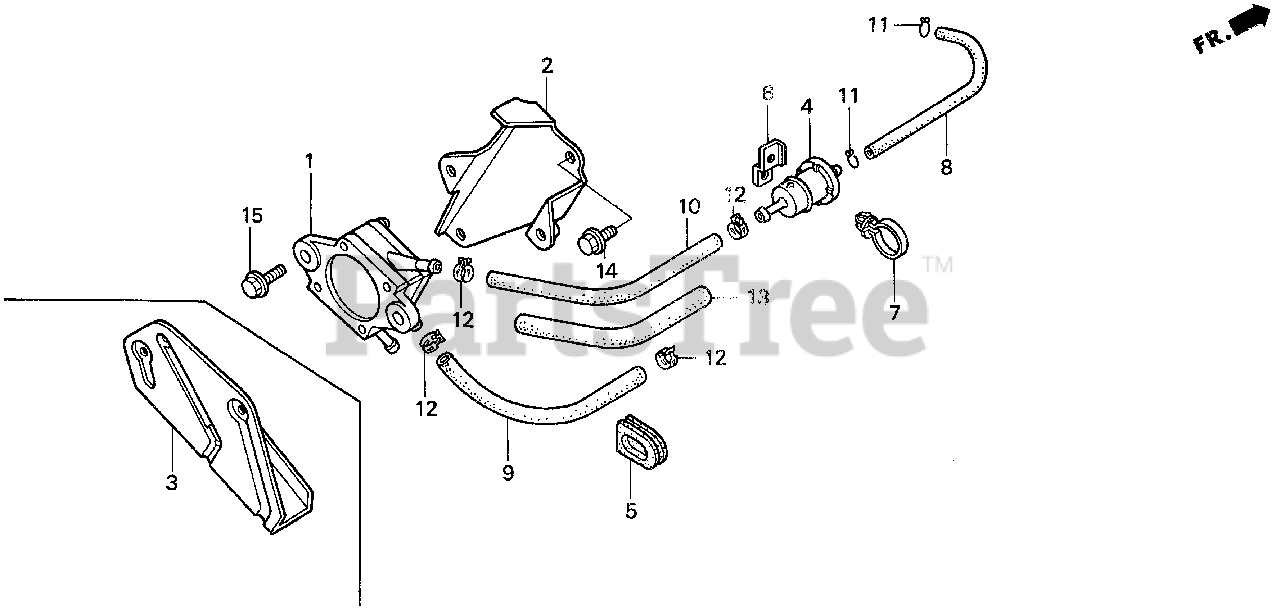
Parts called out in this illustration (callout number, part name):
1	PUMP ASSY., FUEL
2	STAY, FUEL PUMP
4	FILTER, FUEL
5	GROMMET, WIRE
6	BASE, CLIP
7	CLIP, WIRE HARNESS
8	BULK HOSE, FUEL (4.5X3000) (4.5X110)
9	BULK HOSE, FUEL (5.5X8000) (5.5X195)
10	BULK HOSE, FUEL (5.5X8000) (5.5X215)
11	CLIP, TUBE (B8)
12	CLIP, TUBE (10.5MM)
13	BULK HOSE, VINYL (11X13X3000) (11X13X160)
14	BOLT, FLANGE (6X8)
15	BOLT, FLANGE (6X14)
